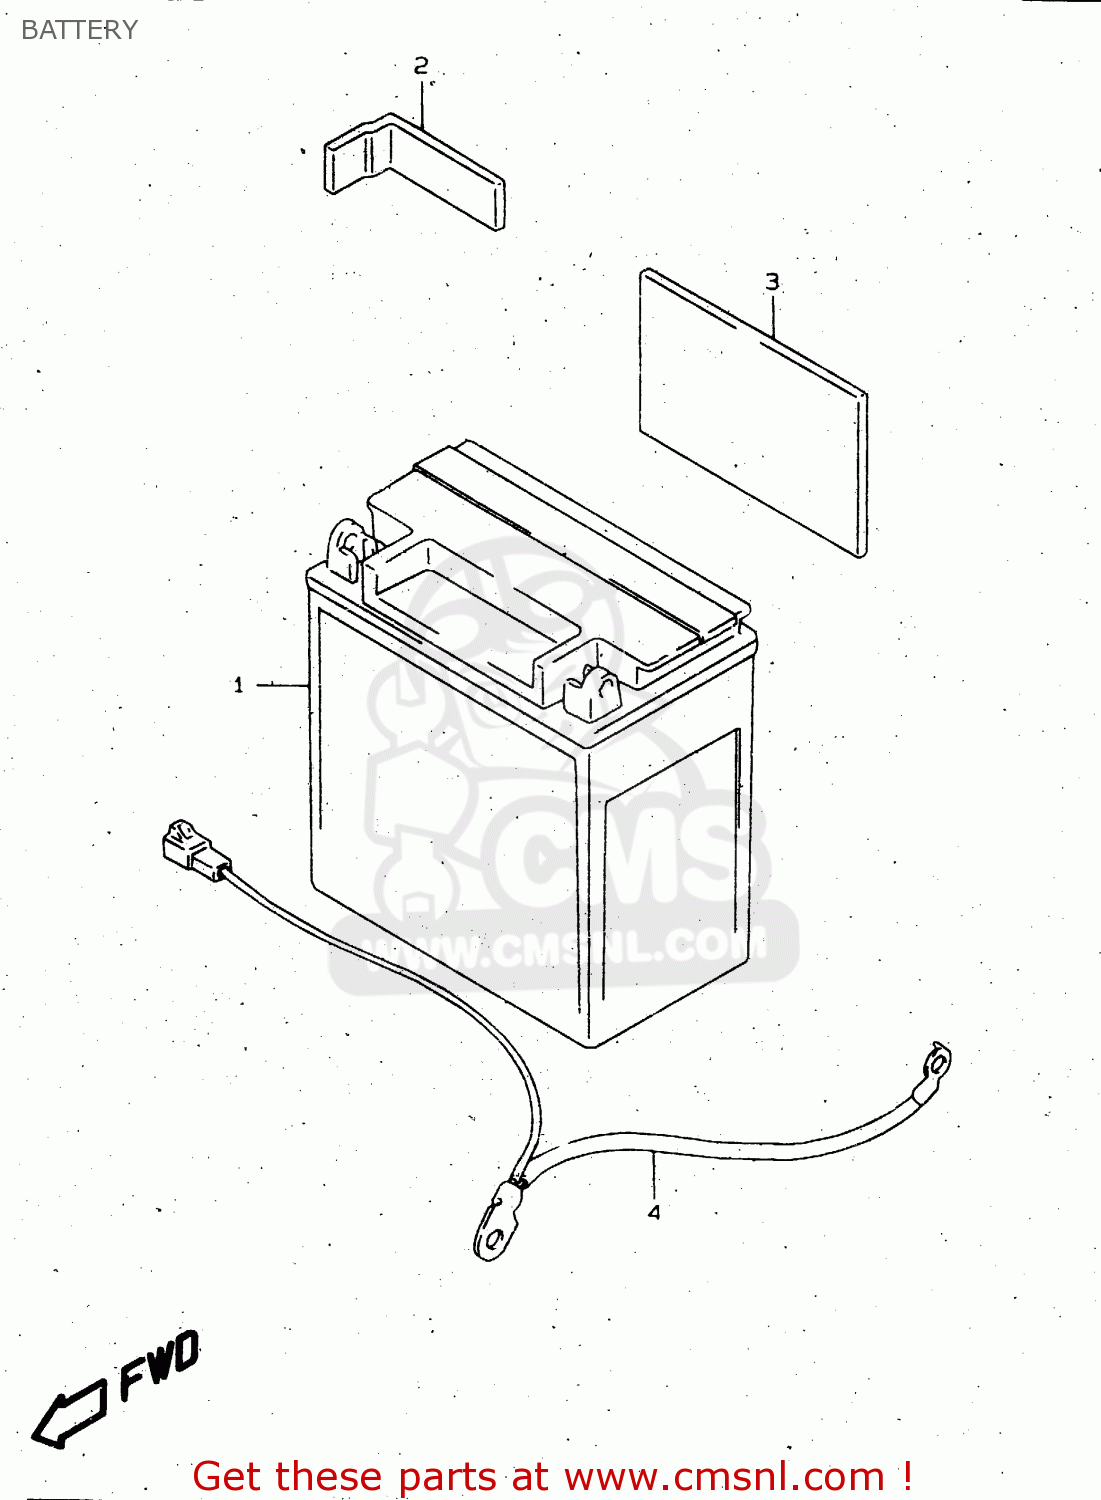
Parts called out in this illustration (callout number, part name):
1	BATTERY ASSEMBLY 12V14AH,F
2	PROTECTOR(80X80X2)
3	PROTECTOR(170X95X3.0)
4	WIRE,BATTERY MINUS LEAD
